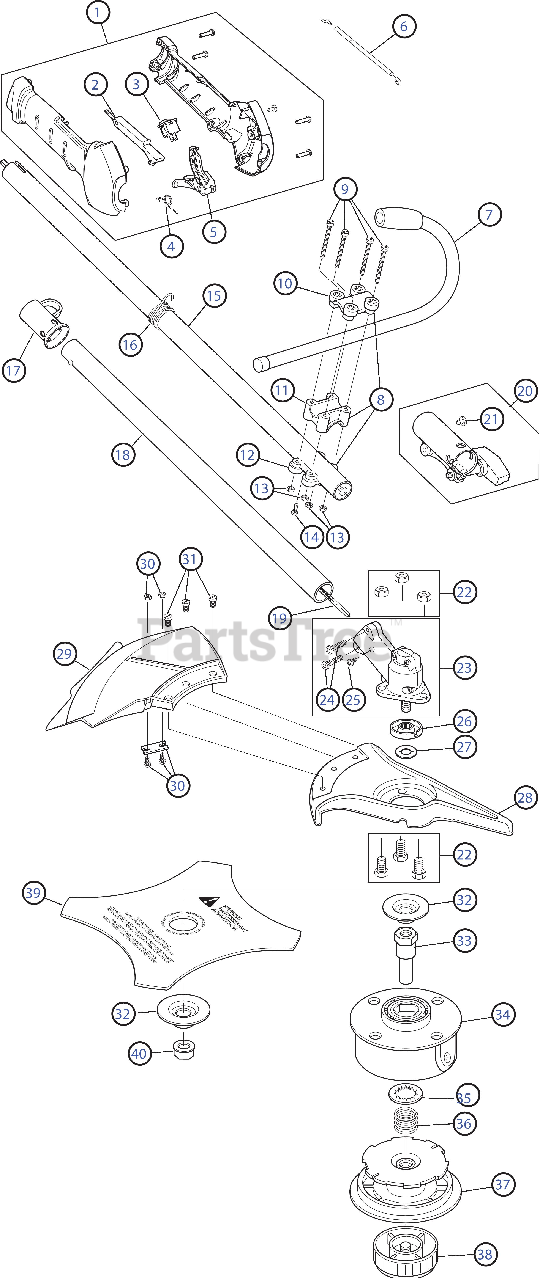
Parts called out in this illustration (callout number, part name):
1	Throttle Housing Assembly
2	Throttle Trigger Lock-Out
3	Switch Assembly
4	Throttle Trigger Spring
5	Throttle Trigger
6	Throttle Cable Assembly
7	J-Handle Assembly
8	J-Handle Bracket Assembly
10	Upper Handle Clamp
11	Middle Handle Clamp
12	Lower Handle Clamp
14	Anti-Rotation Screw
15	Upper Drive Shaft Housing Assembly
16	Harness Clip
18	Lower Drive Shaft Housing Assembly
19	Lower Flexible Drive Shaft
20	Split Boom Coupler
22	Shield Mount Screw Assembly
23	2 Piece Gearbox Assembly
24	Gearbox Mounting Hardware
25	Anti-Rotation Screw
26	Blade Driver
28	Blade Shield / Shield Mount
29	Shield Assembly
30	Blade Assembly
31	Shield Mounting Screw
32	Retaining Washer
33	Spool Shaft
34	Outer Spool Assembly
35	Retainer
38	Bump Head Knob Assembly
39	4-Tooth Blade
